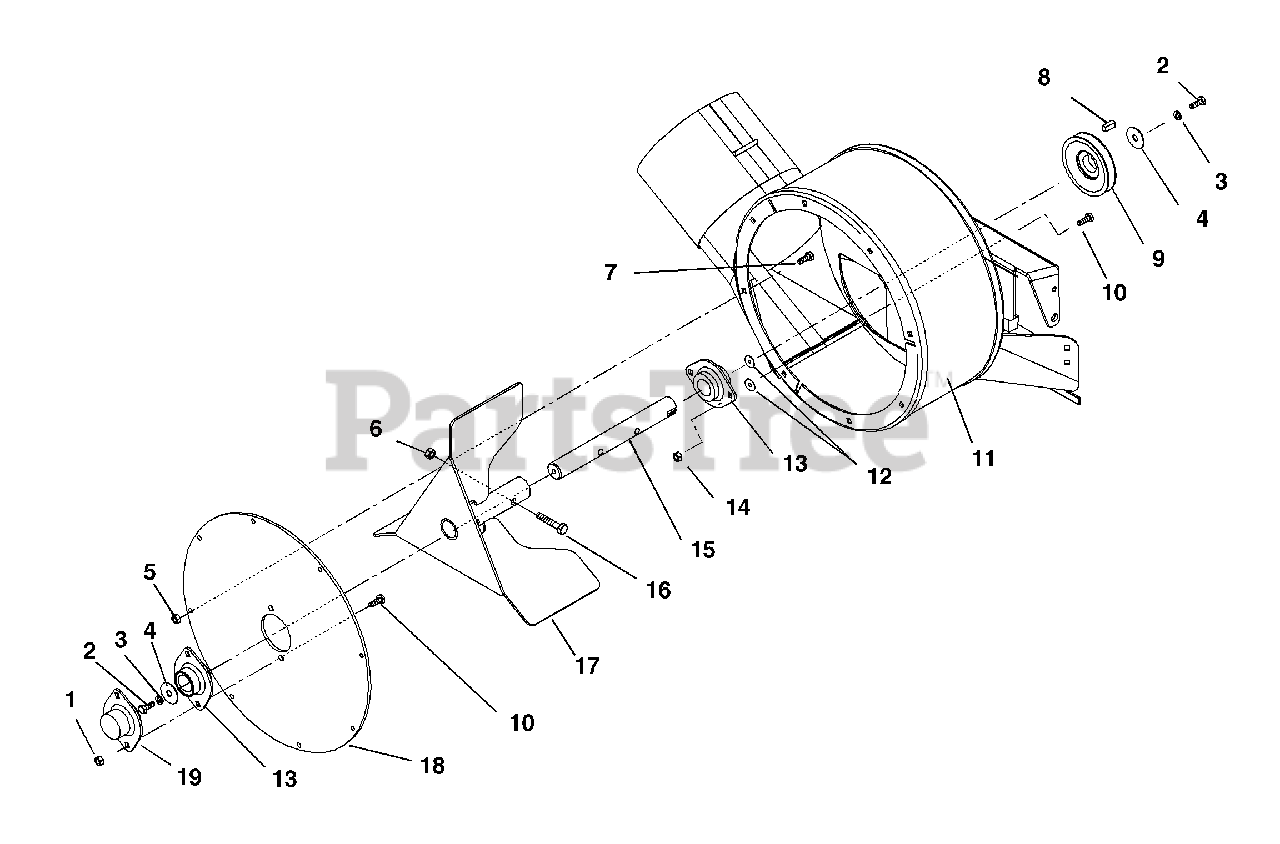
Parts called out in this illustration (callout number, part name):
1	Nut-Locking-Nylon .312-18
2	Bolt-Hex .25-20 x .75 Grade 5
3	Washer-Locking .25 x .062 Regular
4	Washer-Flat-Steel .35 x 1.25 x .048
5	Nut-Locking-Top-Flange .25-20
6	Nut-Locking-Center .31-18
7	Bolt-Round Head Square Neck .25-20 x .50
8	Key-Square .25 x .38 x .25
9	Pulley-Driven 3.50 Dia.
10	Bolt-Hex .31-18 x 1.00
11	Weldment, Blower Housing
12	Washer-Flat-STL .312 x .734 x .06
13	Bearing-2 Bolt x 1.00 Shaft
14	Nut-Locking-Top-Flange .31-18
15	Shaft-Impeller
16	Bolt-Hex .31-18 x 1.75
17	Impeller Complete
18	Cover-Bearing Support
19	Cover-Bearing
